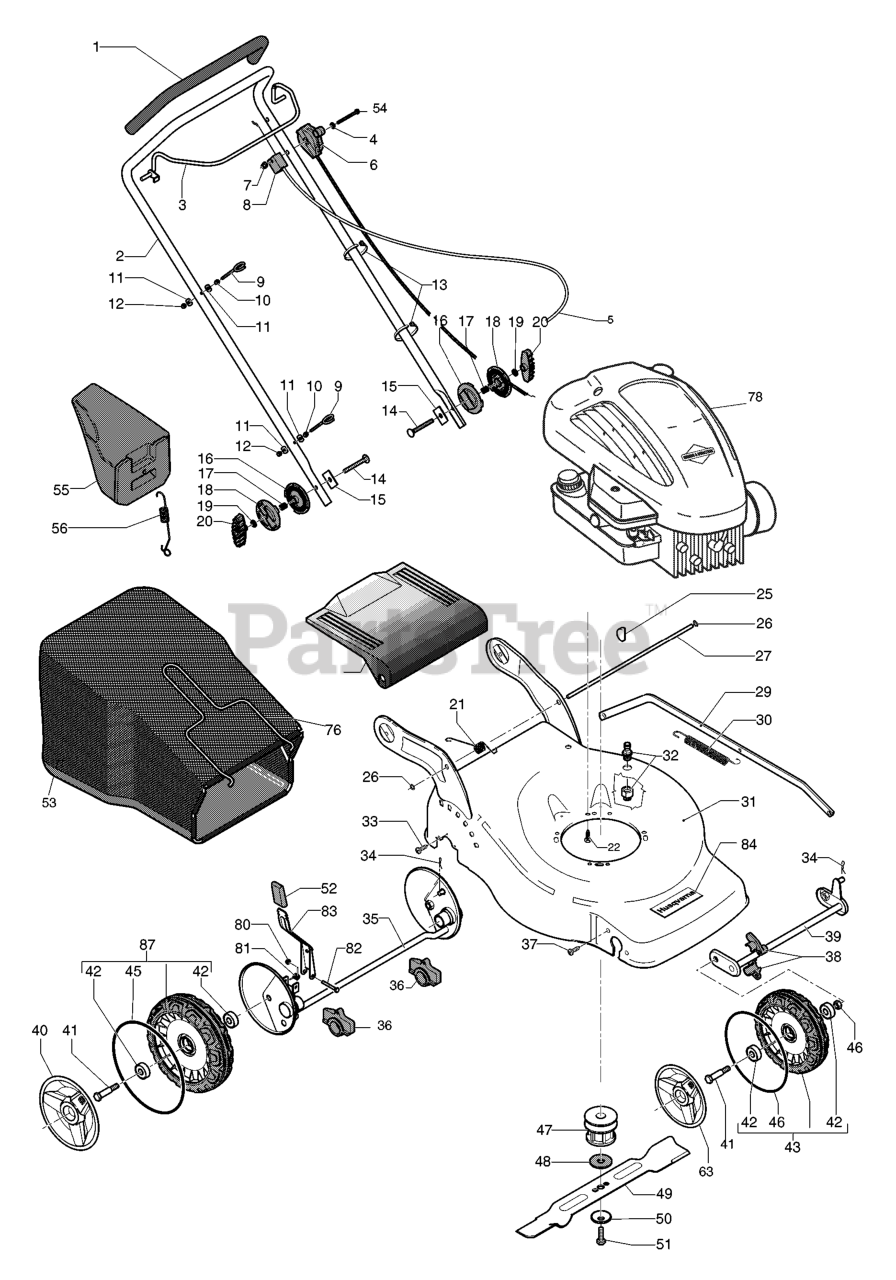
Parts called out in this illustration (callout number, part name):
5	BRAKE WIRE
35	REAR AXLE REAR AXLE WELDED FOR
49	MOWER BLADE COMBI
83	LIFTING LEVER ASSY FOR REAR AX
